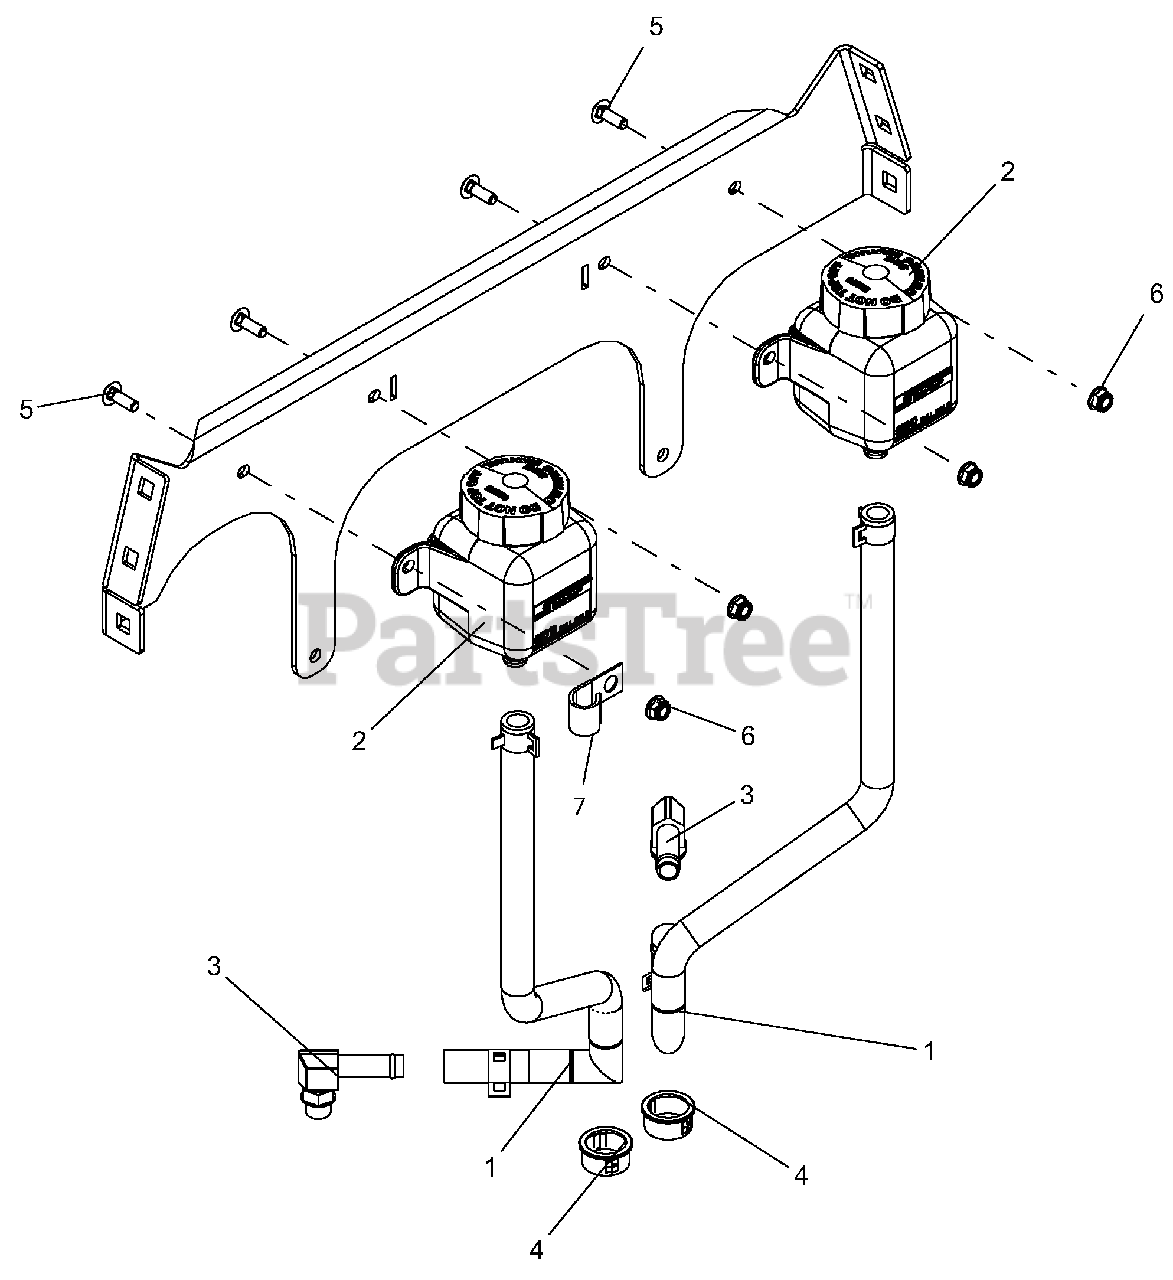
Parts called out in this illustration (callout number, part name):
1	HYDRO, SYSTEM PRO-STANCE
2	TANK, EXPANSION ZT2800
3	FITTING, HYD (90 DEG)
4	BSHG, PANEL SNAP .937X1.109X.56
5	BLT-RDHDSQNK .25-20X.75 G5 YWZC
6	NUT-LK-NYL-FLG .25-20 YWZC
